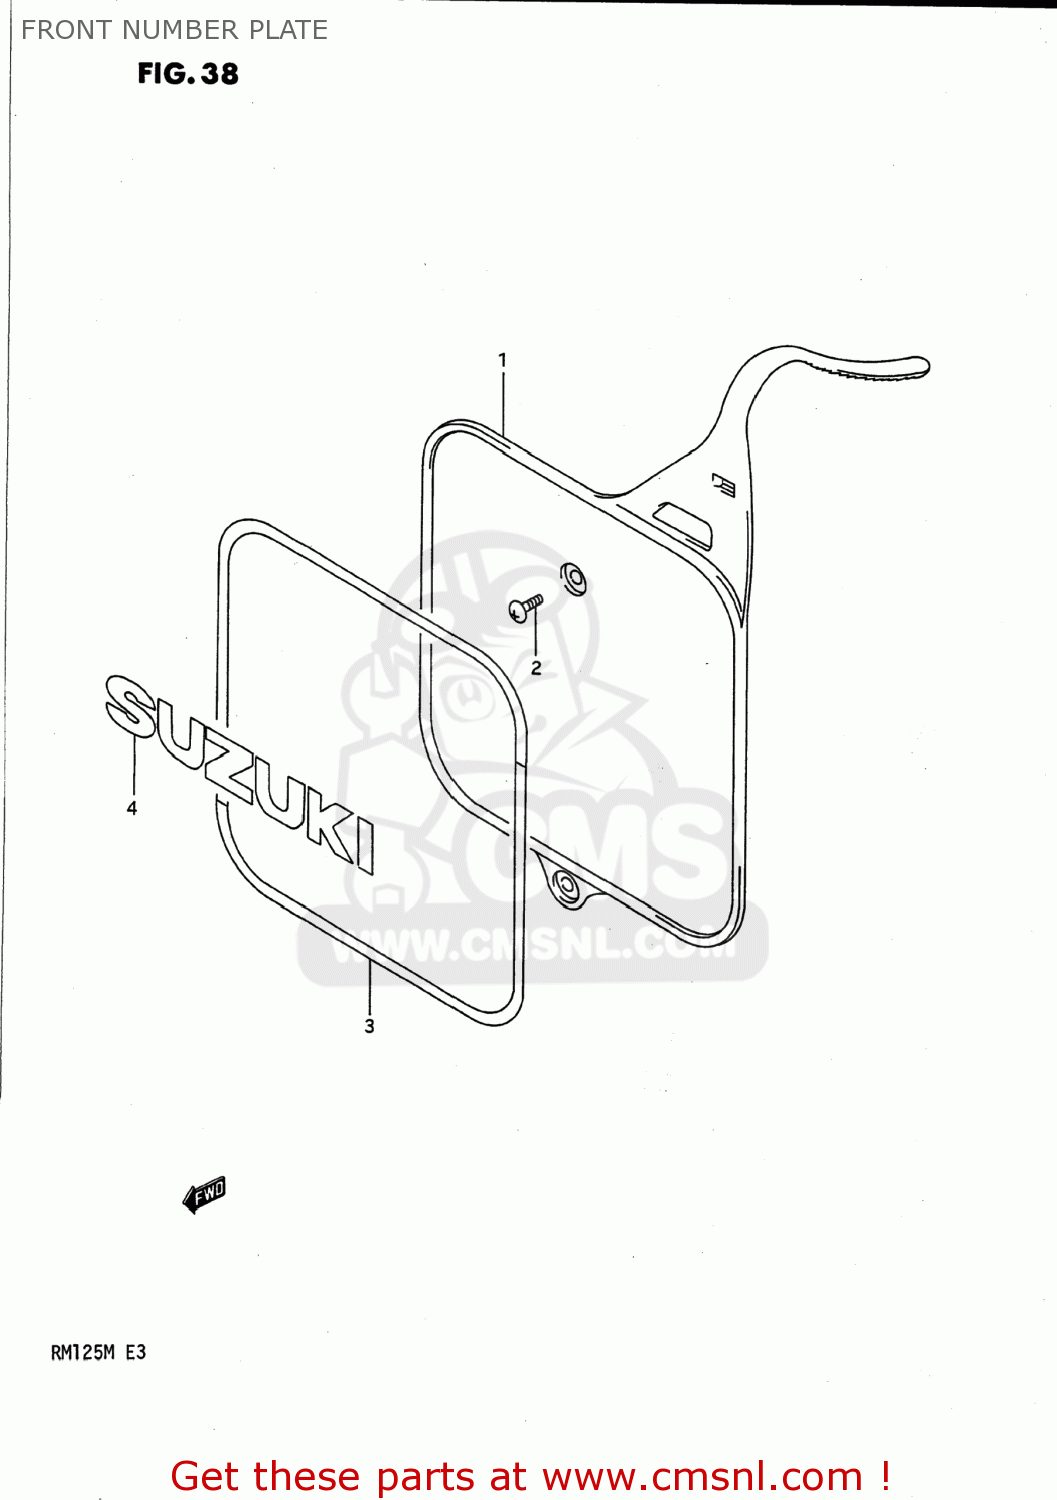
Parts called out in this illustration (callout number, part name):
1	PLATE,NUMBER,FRONT
2	SCREW
3	TAPE SET,FRONT NUMBER
4	EMBLEM,FRONT NUMBER PLATE (SUZUKI)
